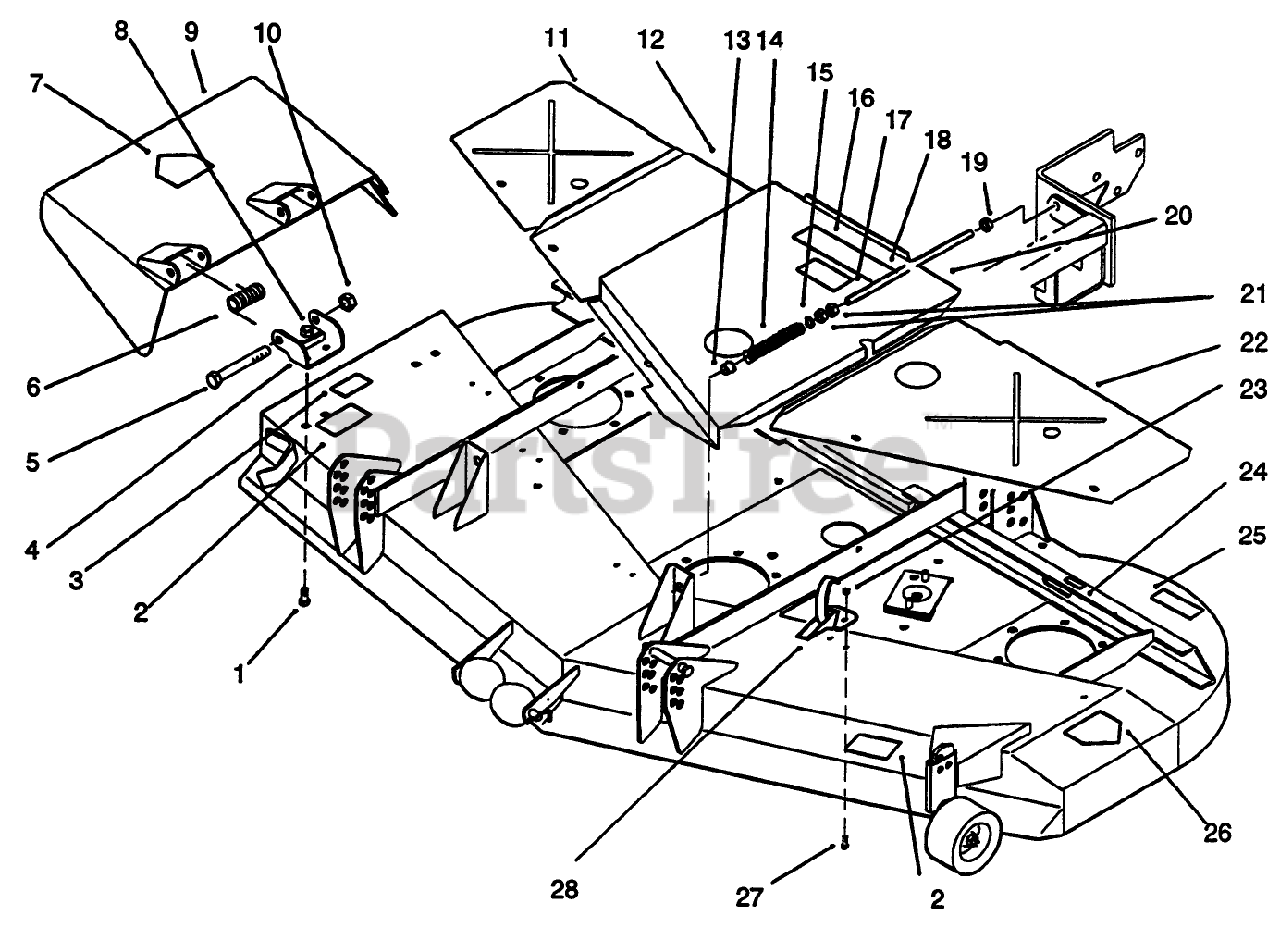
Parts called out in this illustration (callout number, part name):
1	SCREW-CARR
2	DECAL-DANGER, THROWN OBJECT
3	DECAL-DANGER
4	Bracket-Hinge
5	SCREW-HH
6	SPRING
7	DECAL-DANGER
8	NUT-HHF, WHIZ
9	Deflector Assembly (Incl. Ref. #7 & 26)
10	NUT-HEX
11	Cover-Deck R.H.
12	Cover-Deck, Center R.H.
13	BUSHING-FLANGE
14	SPRING
15	WASHER
16	DECAL-PROLINE
17	DECAL
18	ADJUSTING SHAFT
19	NUT-LOCK, NI
20	Cover-Deck, Center L.H.
21	NUT-JAM
22	Cover-Deck L.H.
23	NUT-LOCK, FLANGE
24	DECAL-DANGER
25	DECAL-TORQUE
26	DECAL-DANGER
27	SCREW-HWH
28	CLAMP-SLOTTED
